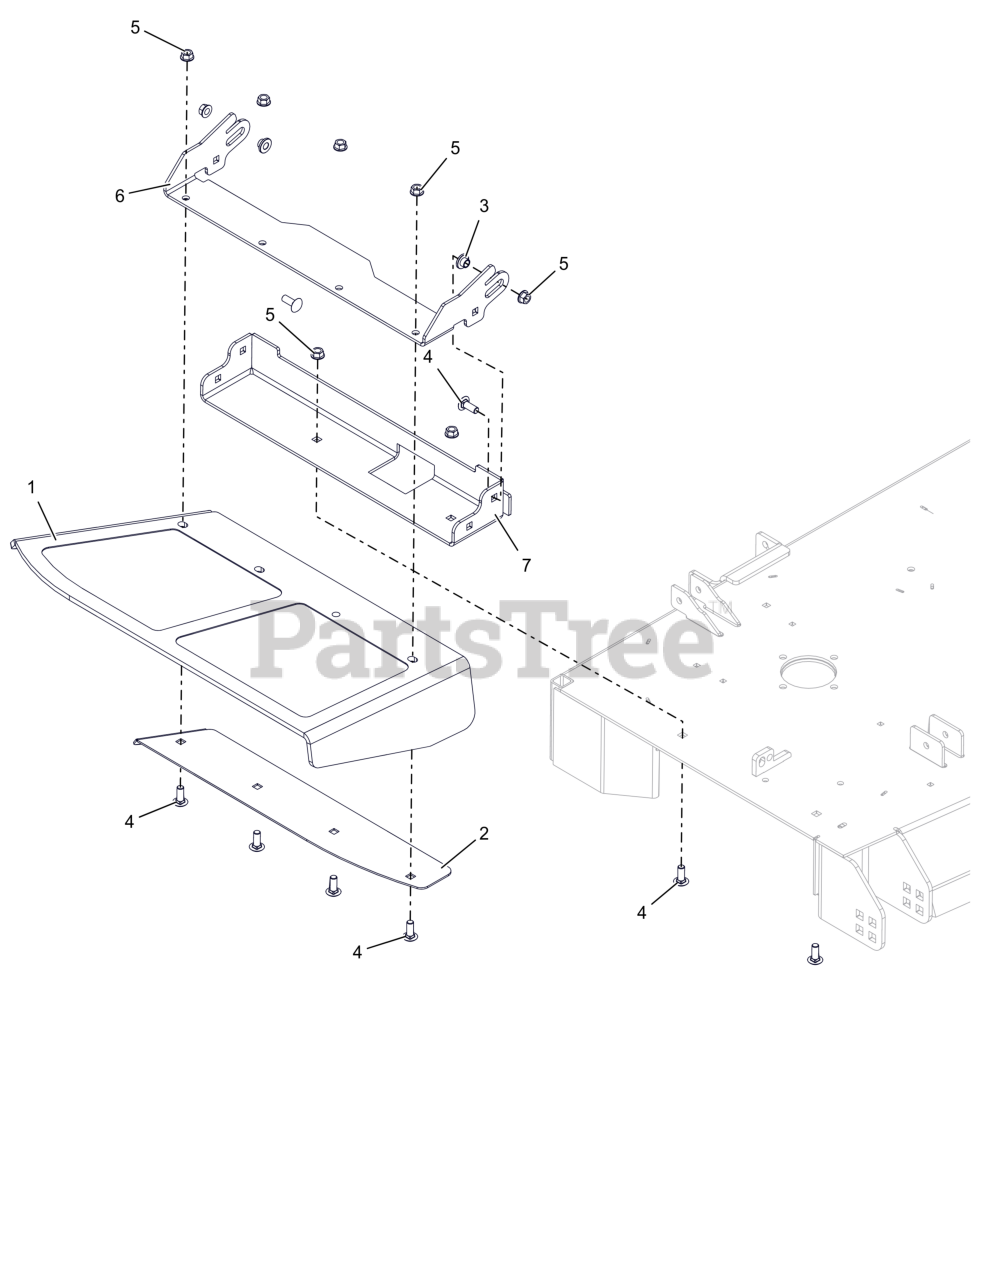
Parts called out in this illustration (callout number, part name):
1	CHUTE, 72" FORMED RUBBER DISCH
2	72" DISCH CHUTE CLAMP PLT -RED
3	BSHG-FLG .385X.500X.875X.406
4	BLT,RHSSN .38-16X1.00 G5 ZCC
5	NUT-LK-CTR-FLG .375-16 GF ZCC
6	BRKT, CHUTE MTG (RED)
7	BASE, DISCHARGE CHUTE MTG (RED) W/ SAFETY DECALS
